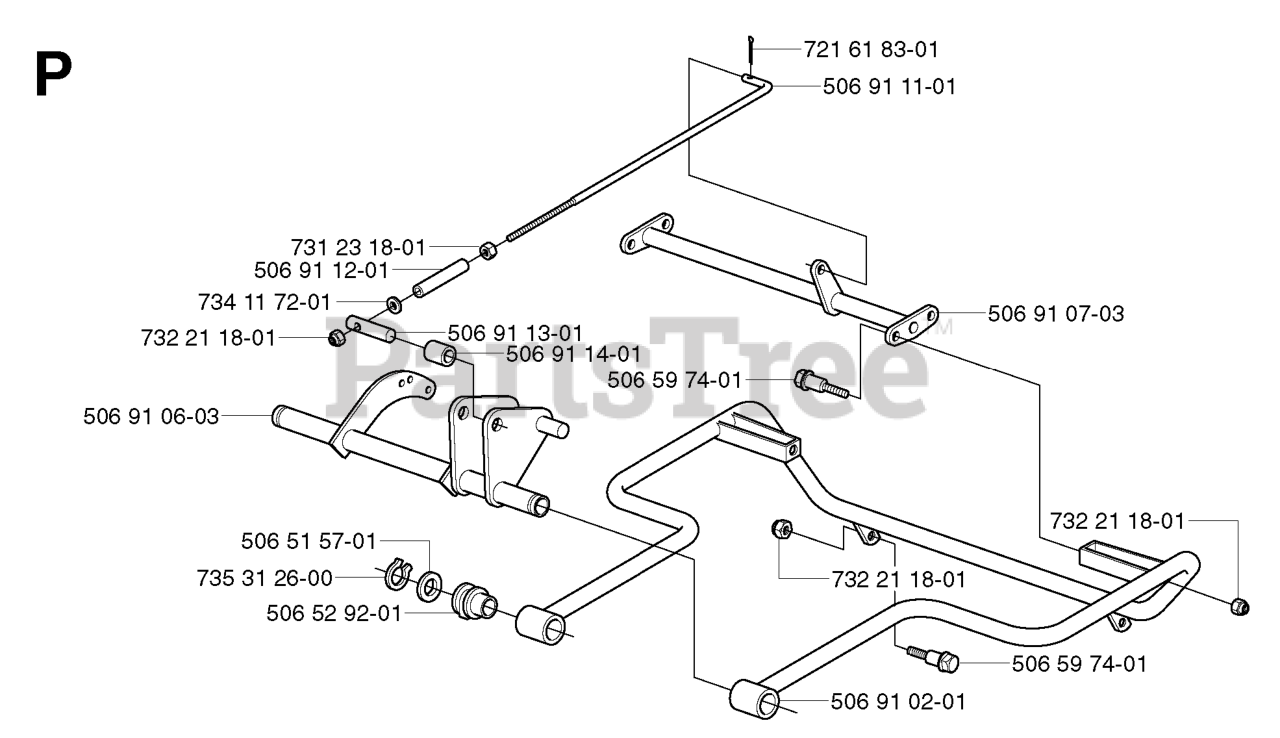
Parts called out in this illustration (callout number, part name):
1	CHOKE CONTROL
2	SCREW LT
4	MUFFLER.SINGLE.B&S.10-12HP
13	REPL BY 532 27 22-93
14	Nipple Pipe 3/8 Npt X 3-1/2
15	ELBOW
16	LOCKWASHER
23	SHIELD.BROWNING.DBR.GUARD
29	KIT.SPARK ARRESTOR 794945 B&S
31	FUEL TANK
32	FUEL CAP
33	HOSE CLAMP
37	LINE.FUEL.20
40	BUSHING.SNAP.NYL.BLK.
44	SCREW HEXWSHR 1/4-20X3/4
45	SCREW, 3/8-16X3/4
62	WASHER.LOCK.HVY.HLCL.SPR.5/16
72	SCREW
78	SCREW.3/8-16
81	NUT
